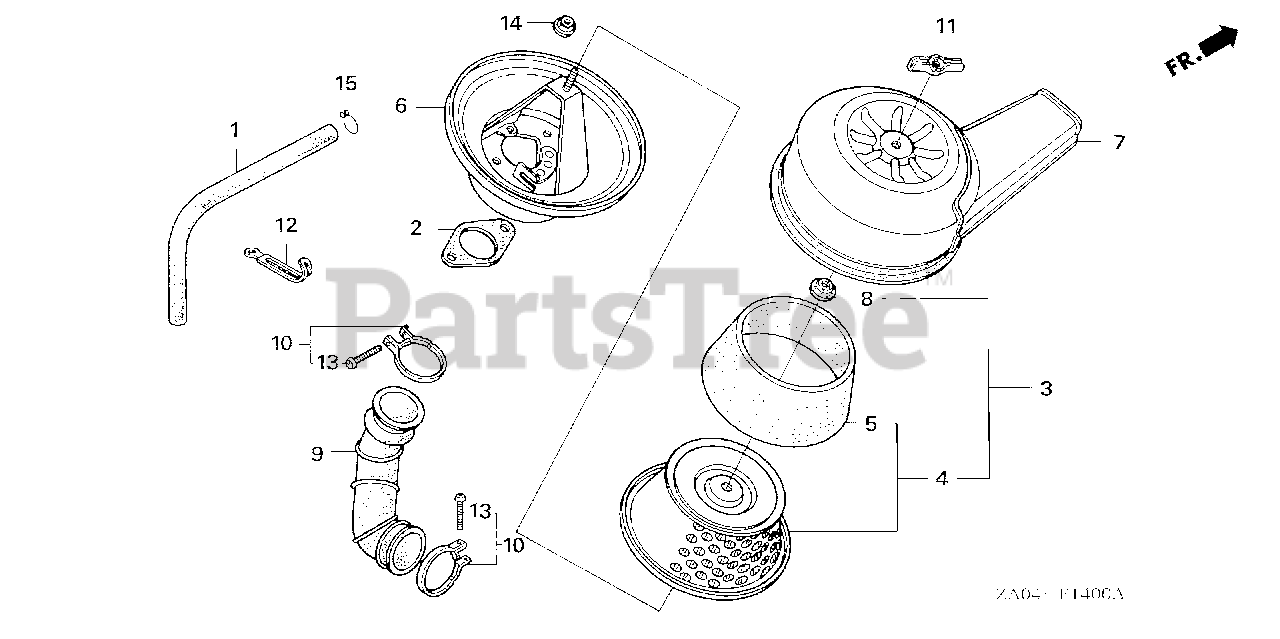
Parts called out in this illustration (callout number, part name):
2	GASKET, AIR CLEANER
3	ELEMENT, AIR CLEANER
4	ELEMENT, AIR CLEANER
5	FILTER (OUTER)
6	HOUSING, AIR CLEANER
7	COVER, AIR CLEANER
8	GROMMET, AIR CLEANER
9	TUBE, AIR CLEANER CONNECTING
10	BAND, CONNECTING TUBE
11	NUT, AIR CLEANER COVER (DACRO COATING)
13	SCREW, PAN (4X16)
14	NUT, FLANGE (6MM)
